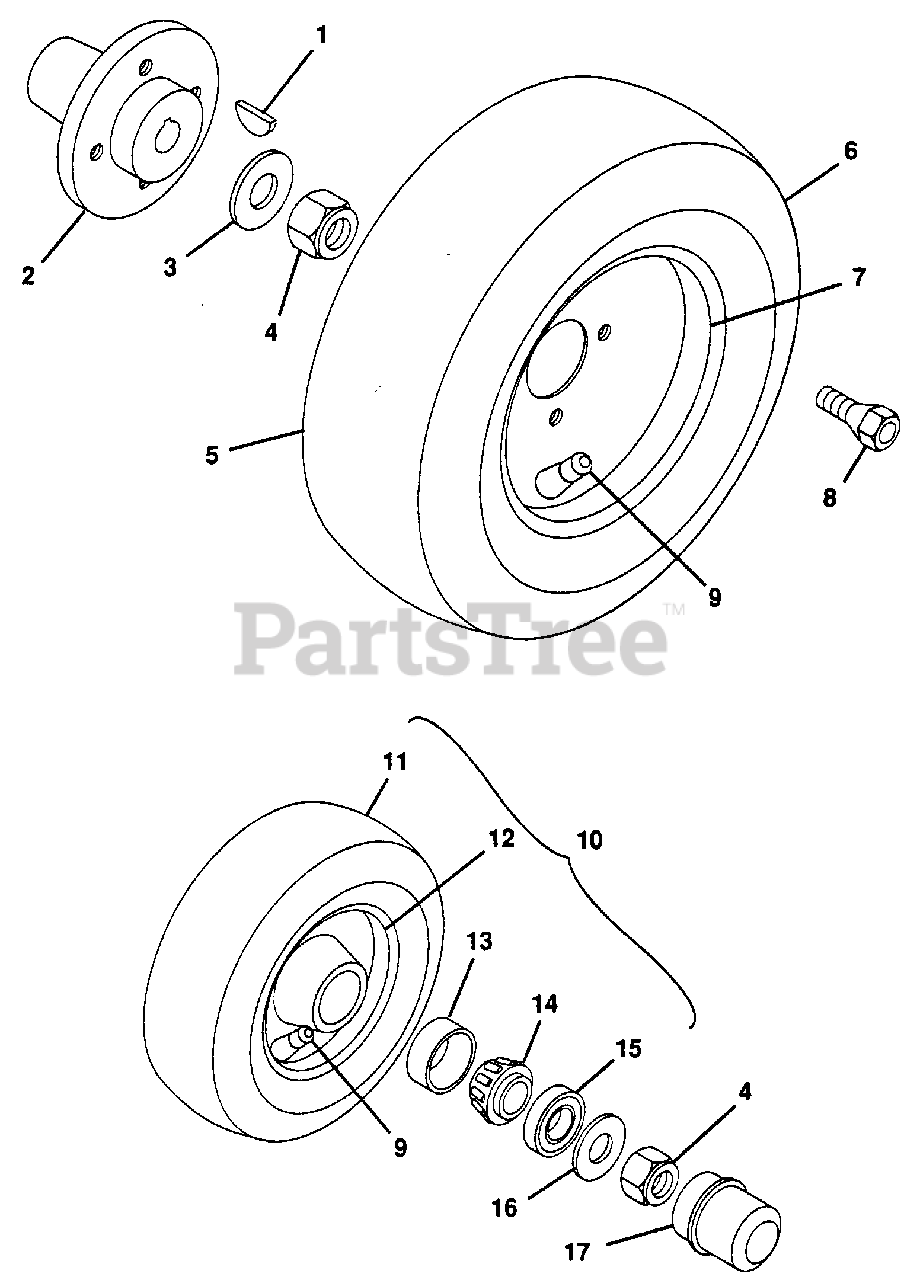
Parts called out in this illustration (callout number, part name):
1	Key, Woodruff .250x2.125 Soft
2	Hub, OFC
3	Washer, Flat .813x2.0x.148
4	Nut, Lock 3/4-10
5	Wheel, Front Pro Master
6	Tire, 20x10.00-10
7	Rim, Pro Master
8	Stud, Wheel
9	Assembly, Valve Stem
10	Wheel, Pro Master Rear
11	Tire, 16x4.80-8
12	Wheel
13	Bearing, Cup
14	Bearing, Cone
15	Seal, Wheel
16	Washer, Flat .812x1.496x.134
17	Cap
